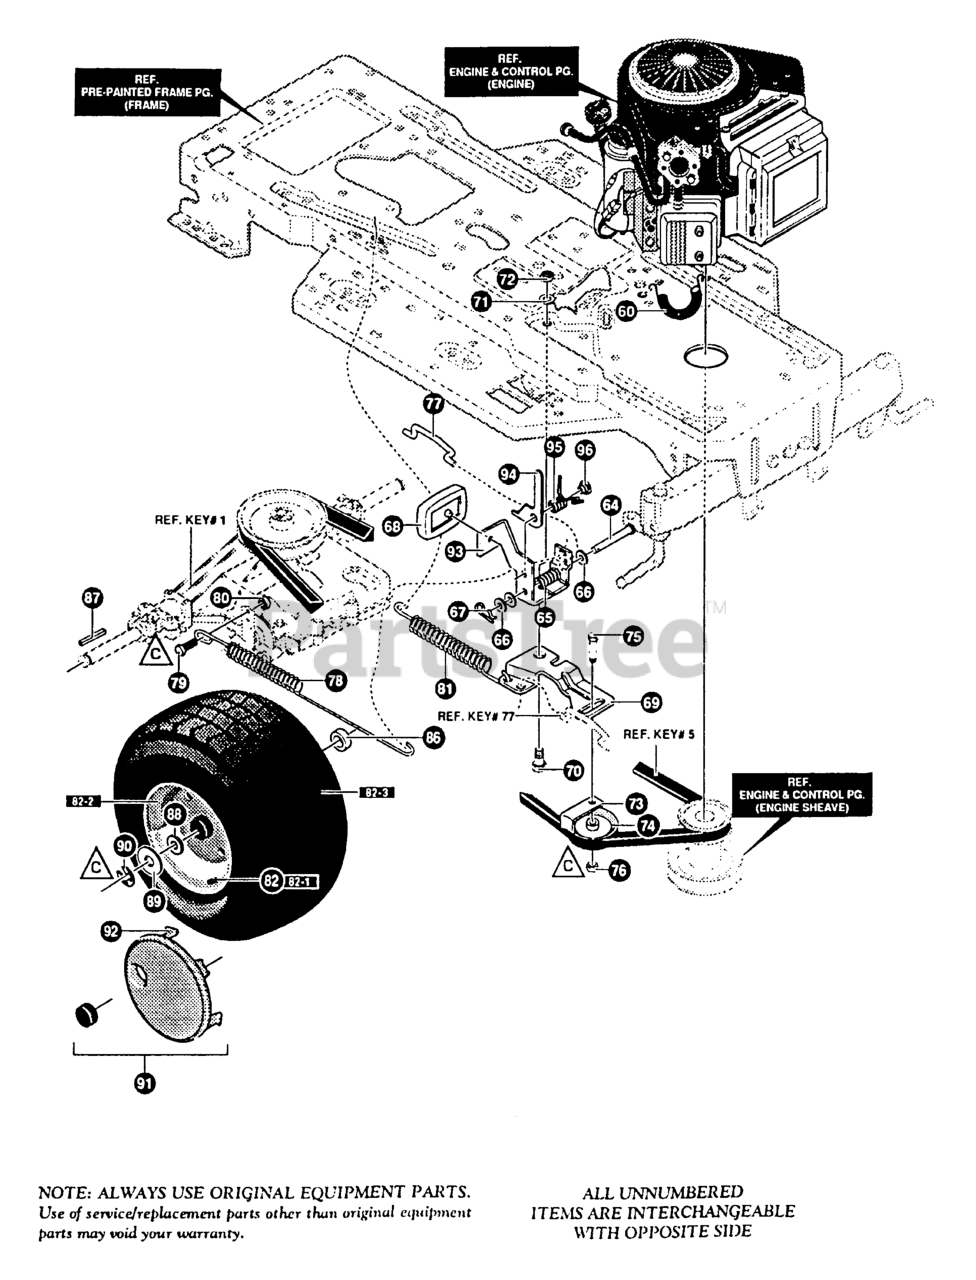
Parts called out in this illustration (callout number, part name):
60	SPRING, DRAG LINK
64	PIN, CLEVIS
65	SPRING, BRAKE PEDAL
66	WASHER, FLAT .504 X .75 X .059
67	PIN, HAIR
68	PAD, CLUTCH BRAKE W/PRINTING
69	ARM, IDLER TRACTION
70	BOLT, .625 X .135
71	WASHER, FLAT .333 X .87 X .119
72	NUT, 5/16-18
73	RETAINER, BELT
74	PULLEY, IDLER
75	BOLT, 3/8-16 X 1.50
76	NUT, 3/8-16
77	ROD, CLUTCH
78	SPRING, BRAKE
79	BOLT, .495 X .31
80	NUT, 5/16-18
81	SPRING, CLUTCH
81-2	RIM, WHEEL
82	TIRE & RIM ASSEMBLY, 20"
82-1	VALVE STEM
82-3	TIRE, 10"
86	SPACER
87	KEY, SQUARE
88	WASHER, FLAT .755 X 1.31 X .075
89	WASHER, FLAT .755 X 1.53 X .07
90	RING, RETEX
91	HUB CAP, 8"
92	CLIP, HUBCAP TINN
93	PEDAL CLUTCH/BRAKE
94	LEVER, PARK BRAKE
95	SPRING, PARKING BRAKE
96	RIVET
